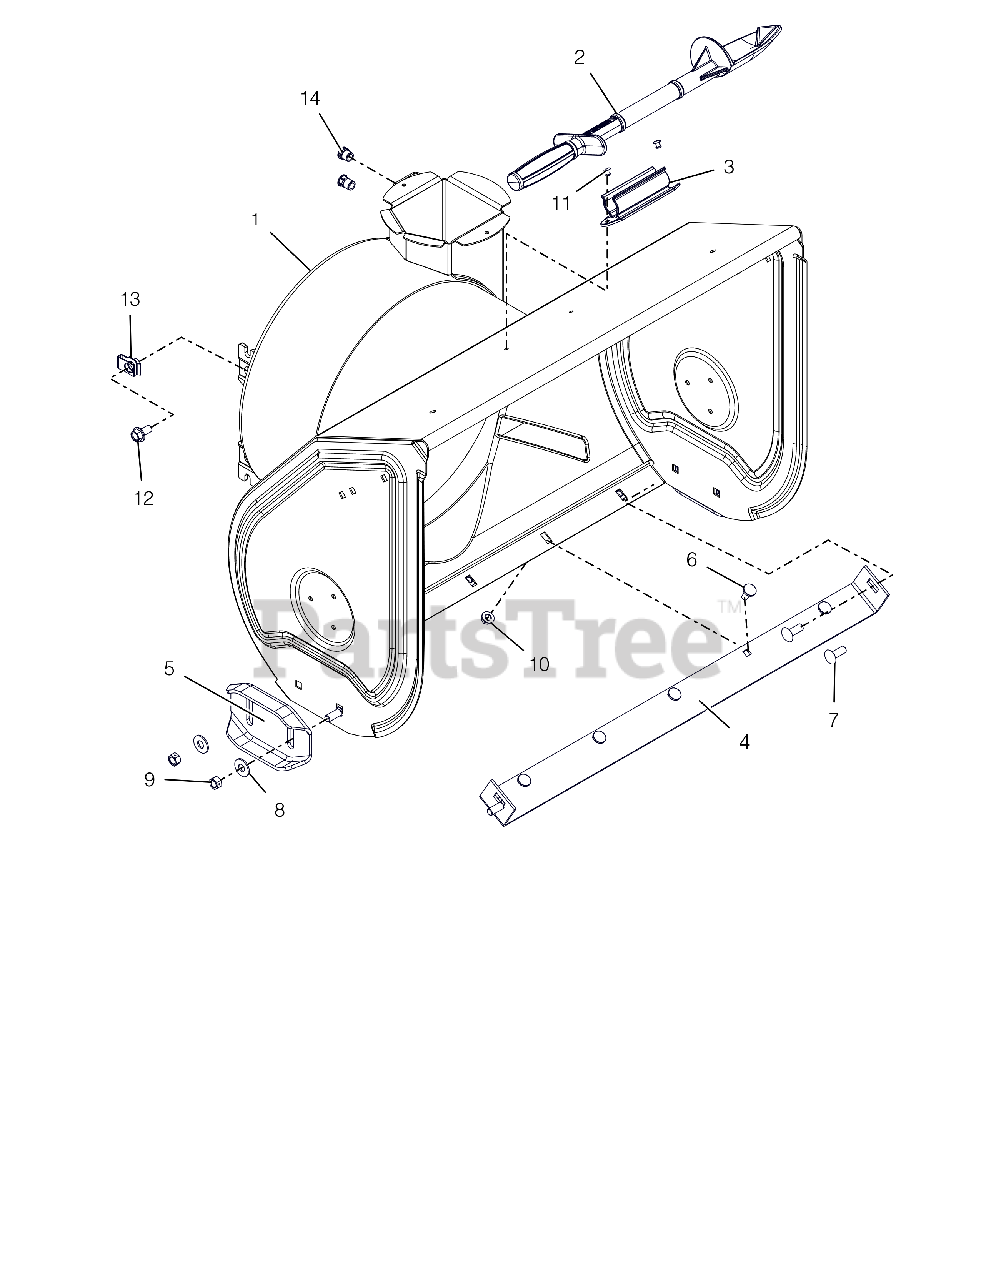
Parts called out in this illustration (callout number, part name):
1	BLOWER HOUSING W/DECAL 28"
2	DEVICE, SNOW CLEAN OUT
3	MOUNT, SNOW CLEAN OUT
4	BLADE, SCRAPER - 28"
5	SKID SHOE, REVERSIBLE - ORANGE
6	BOLT, MODIFIED HEAD CARRIAGE
7	@BLT-RDHDSHSQNK.38-16X1.0 G5YZ
8	@WSHR-FL-STL.438X1.00X.083 YWZ
9	@NUT-LK-CTR .38-16 YWZC
10	@NUT-LK-TOP-FLG .31-18 YWZC
11	RVT-POP .187 YZ
12	BLT-SERHFWH .38-16X.75 YWZC
13	NUT-RTNR .375-16X.37
14	NUT, THREADED INSERT .38-16
